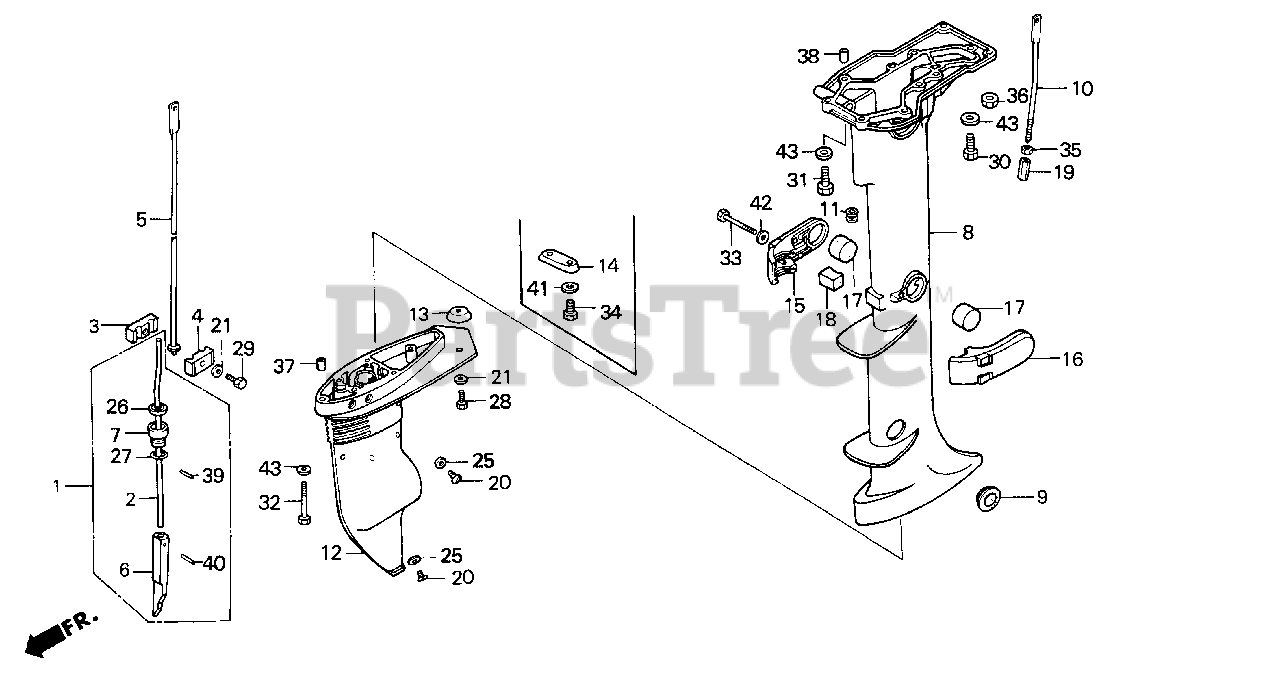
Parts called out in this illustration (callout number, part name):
1	ROD B, SHIFT
2	ROD B, SHIFT
3	JOINT, R. SHIFT ROD
4	JOINT, L. SHIFT ROD
5	ROD A, SHIFT (S)
7	HOLDER, SEAL
8	CASE, EXTENSION *NH282MU* (S) (OYSTER SILVER METALLIC-U)
9	GROMMET, EXTENSION
10	SHAFT, REVERSE LOCK
11	GROMMET, LOCK SHAFT
12	CASE ASSY., GEAR (15") *NH282MU* (OYSTER SILVER METALLIC-U)
14	METAL, ANODE
15	HOUSING, R. MOUNTING (LOWER) *NH282MU* (OYSTER SILVER METALLIC-U)
16	HOUSING, L. MOUNTING (LOWER) *NH282MU* (OYSTER SILVER METALLIC-U)
17	RUBBER A, MOUNTING (LOWER)
18	RUBBER B, MOUNTING (LOWER)
19	NUT, REVERSE LOCK
20	BOLT, OIL CHECK (8X8)
21	WASHER, PLAIN (6MM)
25	WASHER, NYLON (8MM)
26	SEAL, WATER (6MM)
27	O-RING (10.8X2.4) (ARAI)
29	BOLT, HEX. (6X16)
30	BOLT, HEX. (6X32)
31	BOLT, HEX. (6X40)
32	BOLT, HEX. (6X50)
33	BOLT, HEX. (6X50)
34	BOLT, HEX. (6X18)
35	NUT, HEX. (5MM)
36	NUT, HEX. (6MM)
37	PIN A, DOWEL (8X14)
38	PIN, DOWEL (8X16)
39	PIN, SPRING (2.5X10)
40	ROLLER (2.5X11.8)
41	WASHER, PLAIN (6MM)
42	WASHER, PLAIN (6MM)
43	WASHER, PLAIN (6MM)
